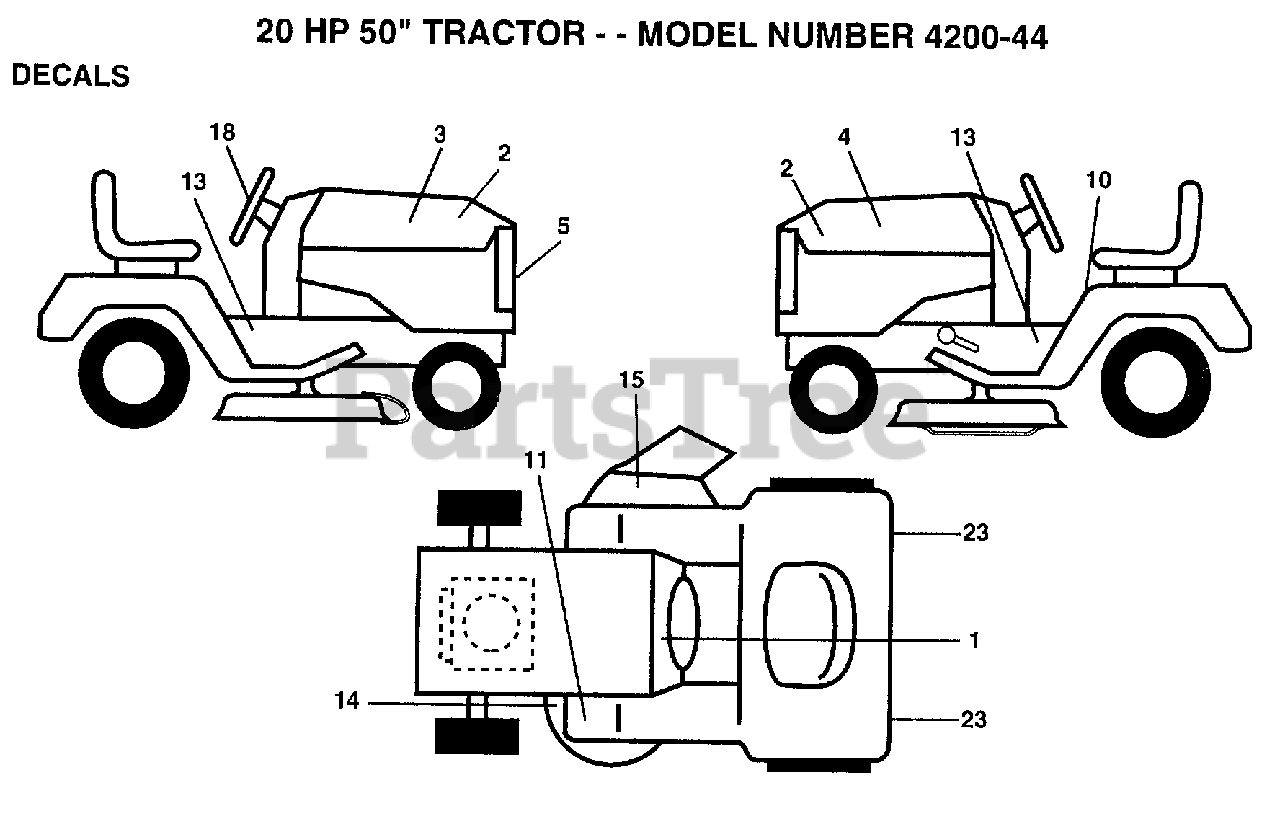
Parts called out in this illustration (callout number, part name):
1	DECAL.DASH.INST.
2	NAMEPLATE LOGO
4	HOOD DECAL LH
5	GRILL DECAL
10	DECAL
13	DECAL.CHASSIS
14	"DECAL.V.BELT.44"""
15	"DECAL, WARNING"
23	REFLECTOR-TAIL YT
